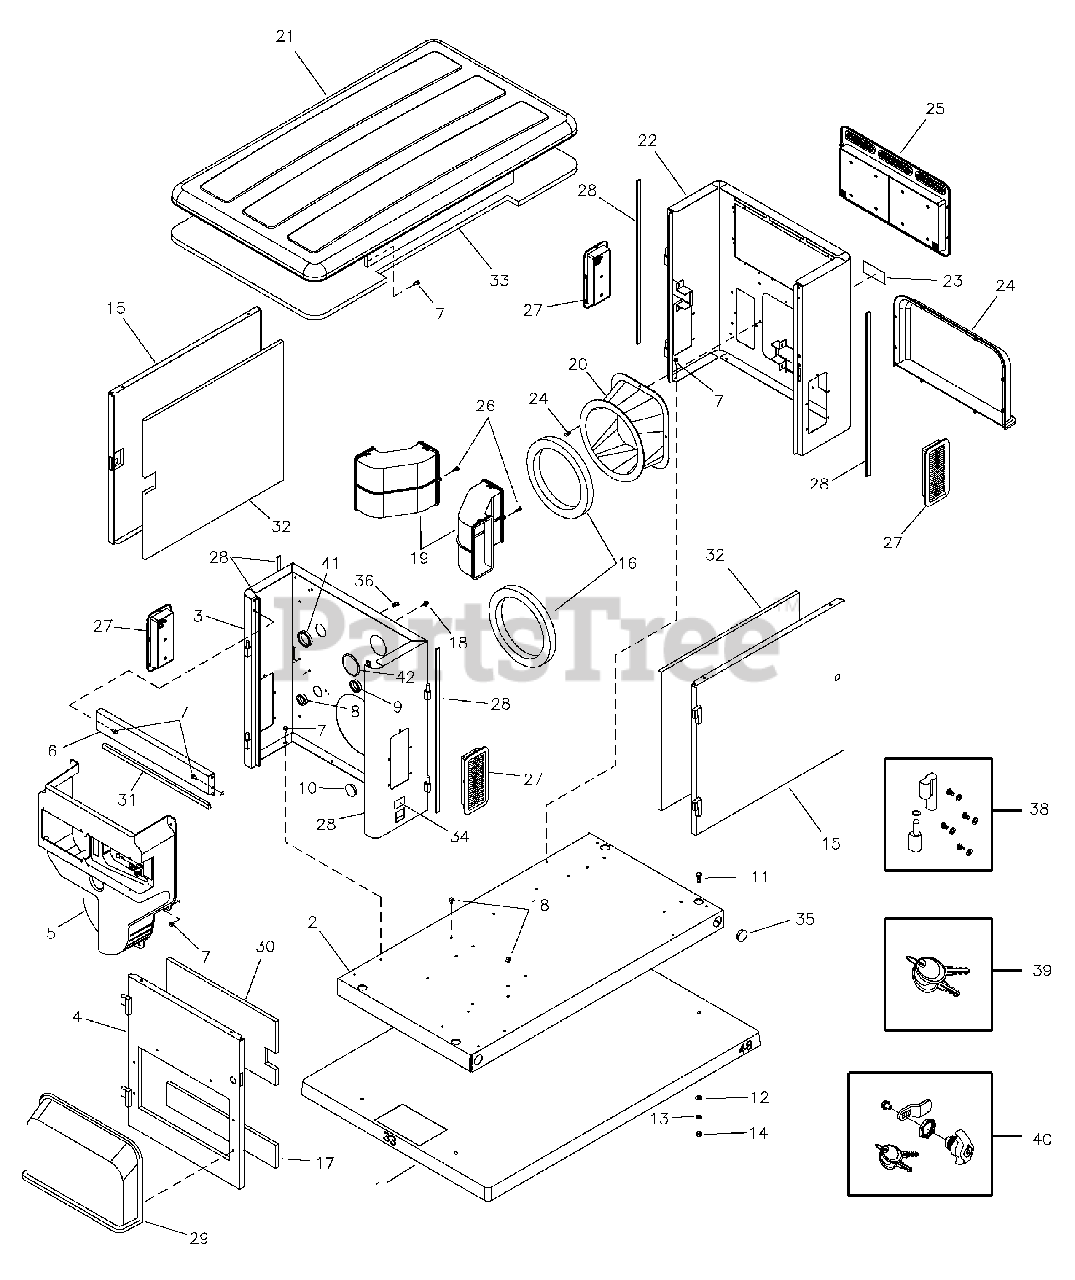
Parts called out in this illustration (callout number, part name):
2	BASE
3	BULKHEAD, Engine
4	DOOR
5	DUCT
6	SUPPORT, Rail
7	BOLT
11	* CAPSCREW, Hex Head, 3/8-16 x 1
12	* WASHER, Flat, 3/8-M10
13	* WASHER, Lock, 3/8
14	* NUT, 3/8-16
15	DOOR
18	MOUNT, Tie Wrap
20	ADAPTER, Alternator
21	ROOF
22	BULKHEAD, Alternator
24	COVER, Air Intake
29	COVER, Air Intake
34	DECAL
